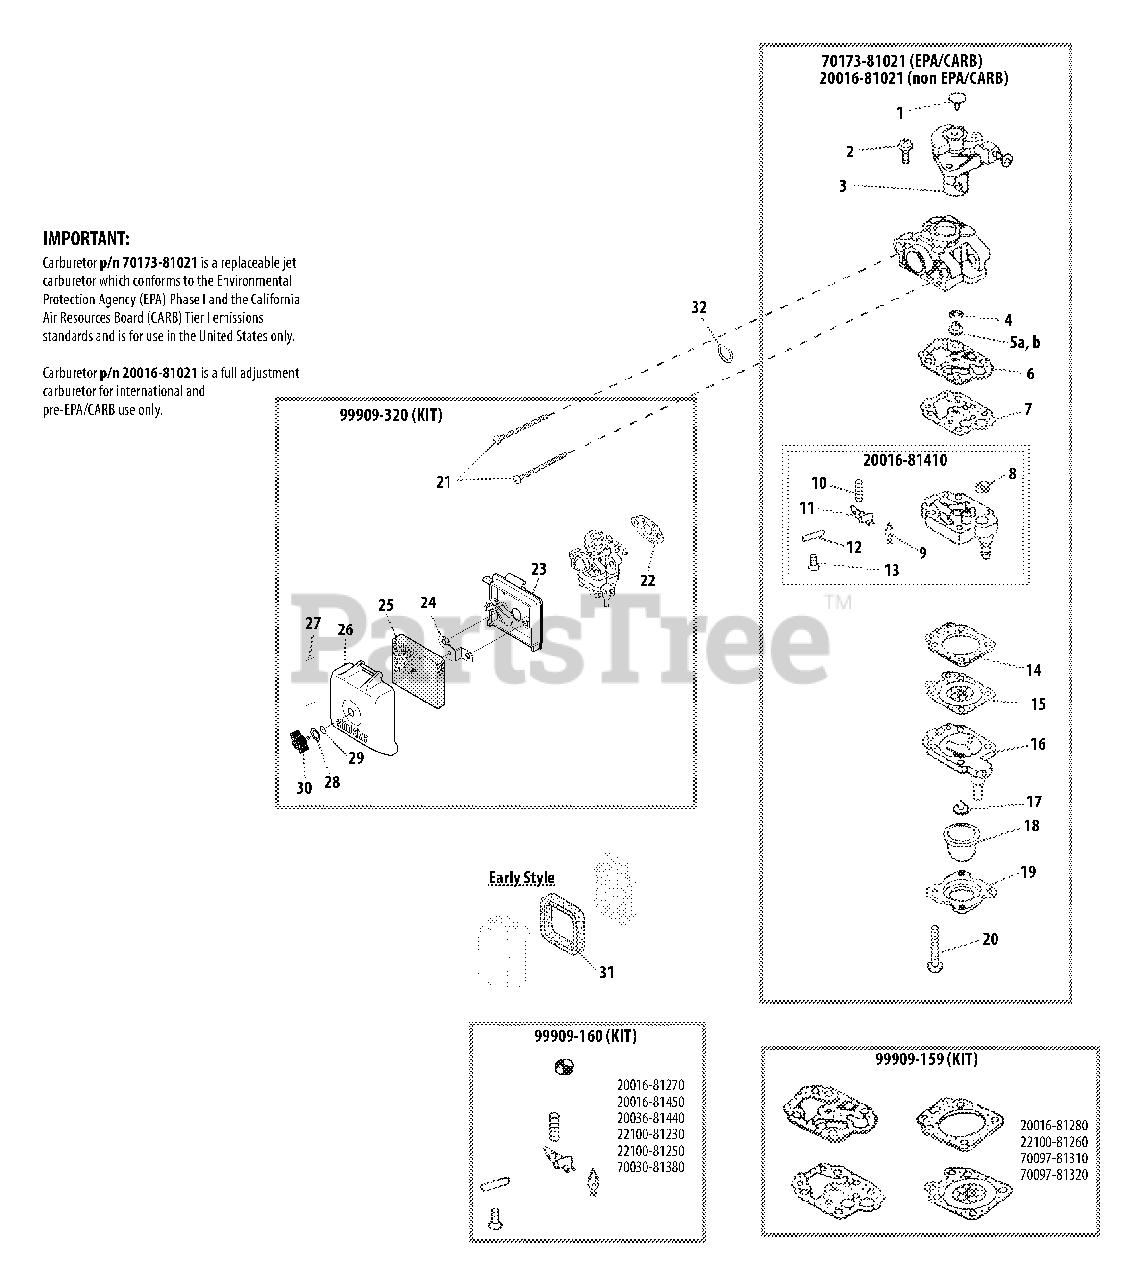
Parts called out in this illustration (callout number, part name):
1	PLUG
2	SCREW, THROTTLE COLLAR
3	THROTTLE VALVE ASSY
4	O-RING
5	MAIN JET - #38
5	JET, MAIN #40
6	GASKET, PUMP
7	DIAPHRAGM, PUMP
8	SCREEN, FUEL INLET
9	VALVE, INLET NEEDLE
10	SPRING, METERING LEVER
11	LEVER, METERING
12	PIN, METERING LEVER
13	SCREW
14	GASKET, METERING DIAPHRAGM
15	DIAPHRAGM, METERING
16	BODY ASSY, PURGE
17	VALVE, CHECK
18	BULB, PURGE
19	RETAINER, PURGE BULB
20	SCREW
21	SCREW - 5×67
22	GASKET, CARBURETOR
23	CASE, AIR FILTER
24	BRACKET
25	FILTER, AIR
26	COVER, AIR FILTER
27	LABEL, CHOKE
28	WASHER, CONE M6
29	O-RING
30	THUMBSCREW
31	FILTER, AIR
32	O-RING 15
20016-81021	CARBURETOR
20016-81410	BODY ASSY, PUMP
70173-81021	CARBURETOR
99909-159	GASKET / DIAPHRAGM KIT
99909-160	VALVE KIT, INLET NEEDLE
99909-320	AIR FILTER ASSY
